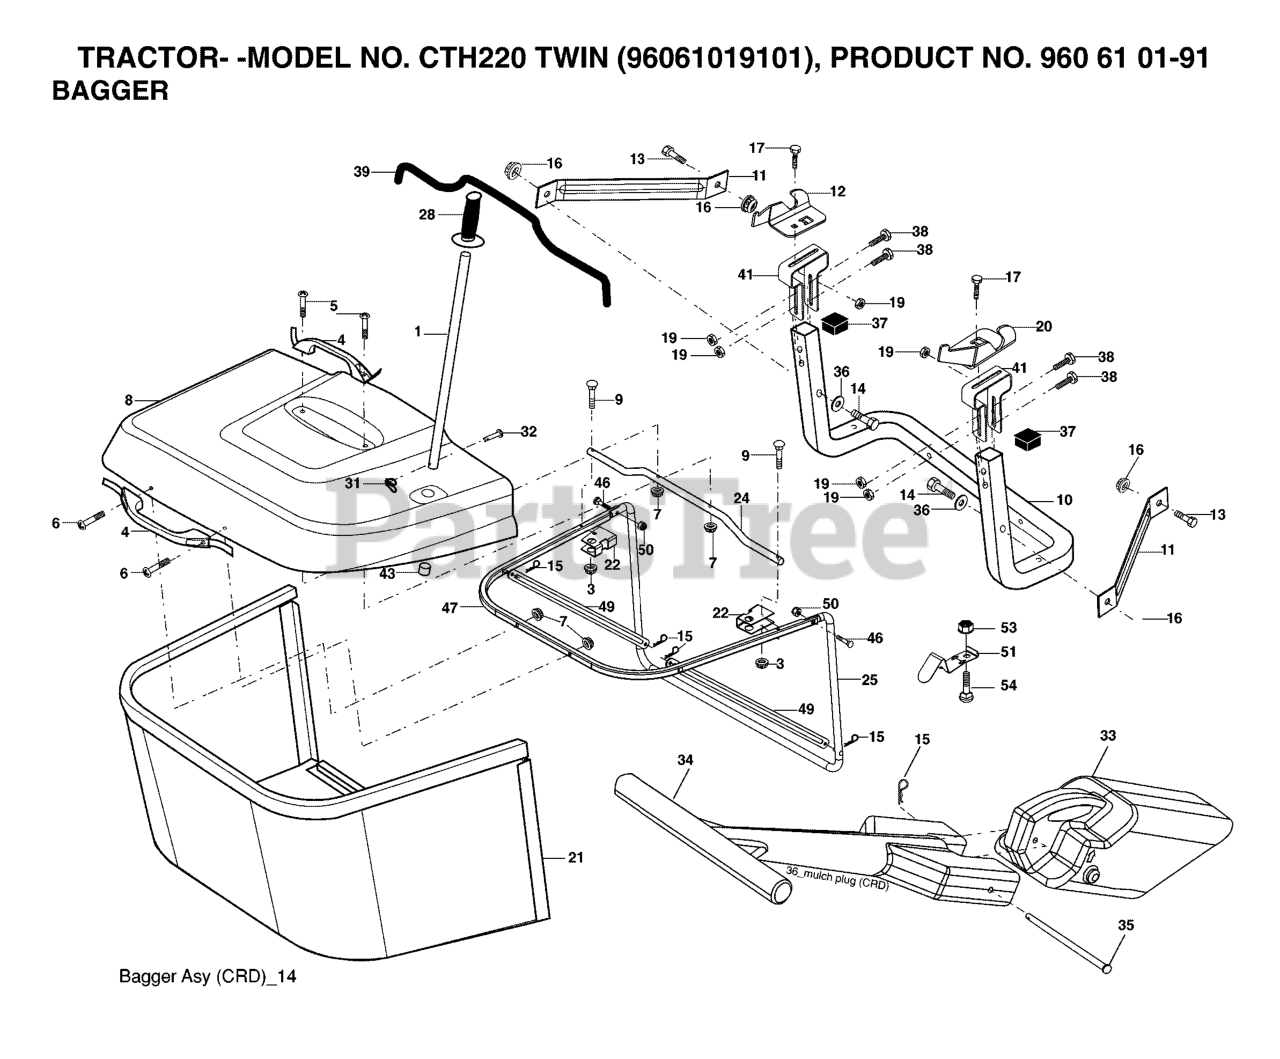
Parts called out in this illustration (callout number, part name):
1	TUBE HANDLE
3	NUT T
4	HANDLE.BAGGER.W/LVRS.BLK.CRD
5	SCREW.PAN.HEAD
6	REPL BY 532 75 00-29
8	COVER.PNT.BGR.CRD.WSLOTS.MS668
9	Bolt Carriage 1/4-20 x 2.25d x Gr.5
10	TUBE
11	BRACKET.SUPPORT.UPPER.BAG.CRD
12	BRKT PIVOT
14	BOLT-HEX EAK
15	RETAINER-SPRNG RB
16	NUT LOCK FLG 3/8-16 UNC
17	RP BOLT 5/16-18 X3/4 ZN/YEL GR
19	NUT LOCK HEX FLANGE 5/16-18
20	BRKT.PIVOT.RH.CRD
21	BAGGER.ASM.CRD.2007
22	BRKT.SIDE.BAG.CRD
24	TUBE.PIVOT.BAG.CRD.BLACK
25	PIPE
28	GRIP.HANDLE.BLACK
31	RETAINER CLIP
32	RIVET,DRILLED
33	MULCH PLUG, CTH150
34	HANDLE.MULCHER.92.CRD (2 2)
36	WASHER
37	Plug Support Bagger CRD
38	BOLT.5/16-18X2.5
39	SEAL.TRIM.37'
41	BRKT.VERT.ADJ.BAGGER.CRD
43	PLUG, TUBING END
46	BOLT.CARRIAGE.5/16-18
47	PIPE
49	ROD
50	NUT.71038.31-18.HEX.NYLOCK
51	LATCH
53	NUT
54	BOLT
